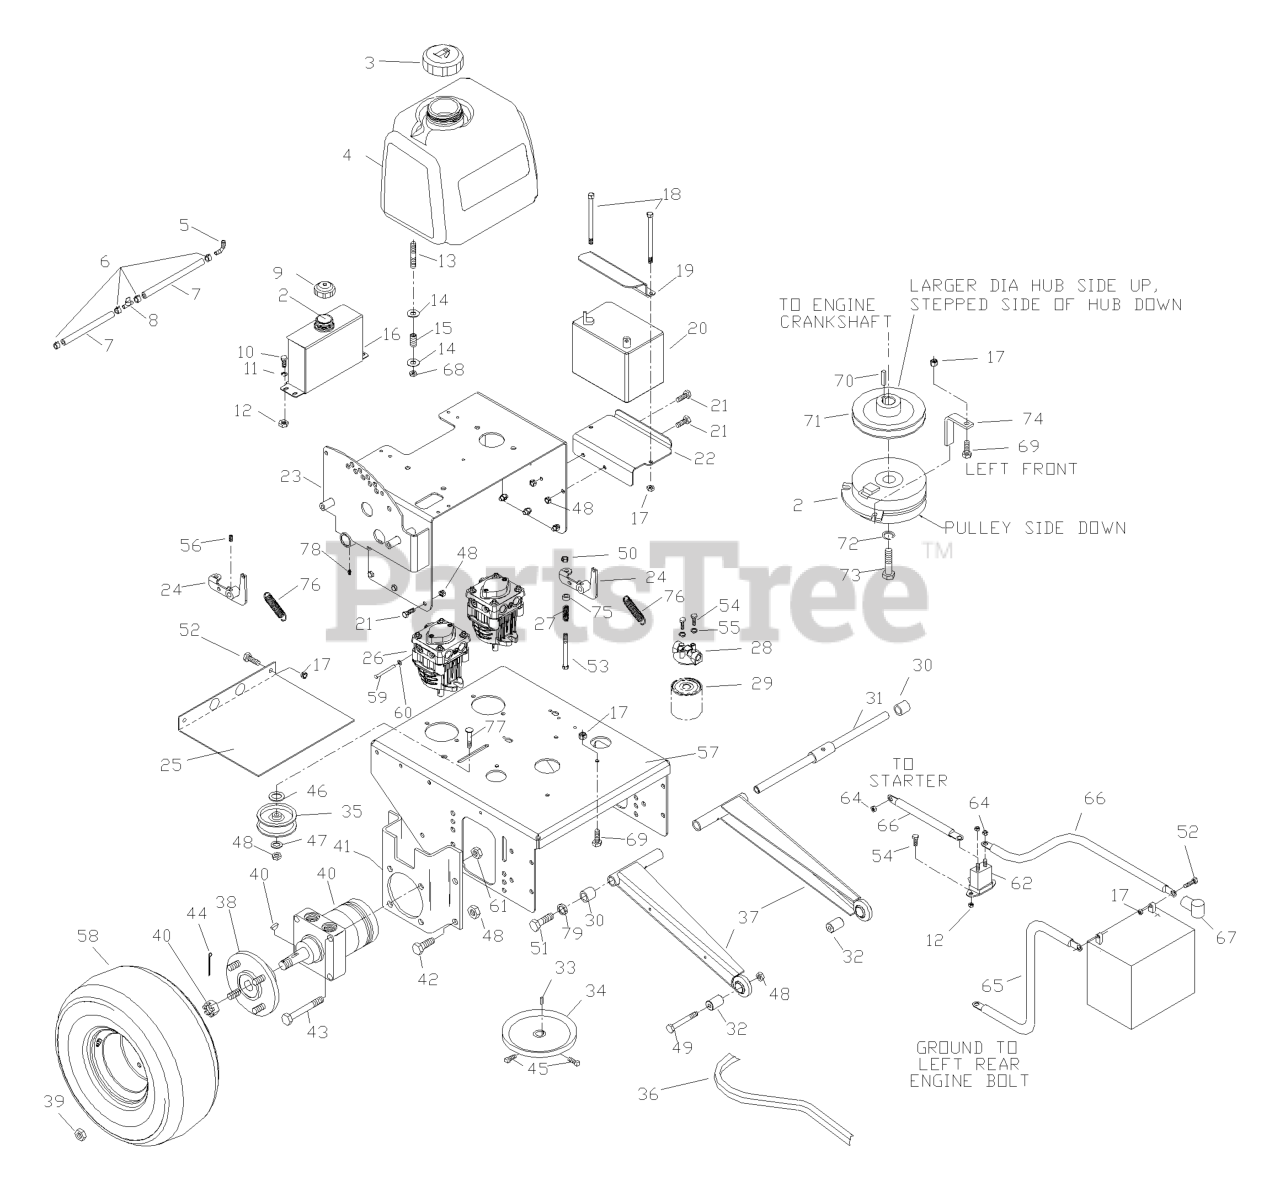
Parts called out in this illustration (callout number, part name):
1	CABLE, THROTTLE (17 KAW.)
3	FUEL CAP ANTI-SPLASH
5	HOSE BARB 90 DEGREE
6	HOSE CLAMP
7	GAS LINE 10"
8	FUEL VALVE
9	HYDRAULIC CAP
10	HCS 1/4C X 3/4 HCS
11	WASHER 1/4 FLAT
12	NUT 1/4C CENTER LOCK
13	STUD, 5/16C
14	WASHER 5/16 FLAT
16	OIL TANK BLK
17	NUT 5/16C CENTERLOCK
18	BOLT - 5/16 X 7
19	BATTERY STRAP
20	BATTERY WET NOT SELLABLE
21	SCREW 3/8C X 3/4 HEX CAP
22	BATTERY TRAY
23	TANK SUPPORT
24	PUMP ARM WELDMENT
25	LOWER BELT SHIELD
26	PUMP
28	FILTER HEAD
29	HYDRAULIC OIL FILTER
31	STRUT SHAFT
32	FRONT SPACER
33	KEY 5 MM SQ X 25 MM
35	IDLER PULLEY
36	TRANSMISSION BELT
37	STRUT WELDMENT
38	HUB.WHEEL.ZTR
39	LUG NUT 1/2F
40	WHEEL MOTOR
40	SEAL KIT - GEN I
41	MOTOR MOUNT
42	HCS 1/2C X 1 1/4 SERRATED HEAD
43	HCS 1/2C X 2 3/4
44	COTTER PIN
45	SCREW 5/16C X 5/8 SQ HEAD
46	WASHER 1/2 FLAT
47	WASHER 3/8 FLAT
48	NUT 3/8C CENTERBLOCK
49	HCS 3/8C X 2 1/4
50	NUT 3/8-16 NYLOC
51	HHCS 1/2-13 X 1
52	HCS 5/16C X 3/4
53	HEX SCREW 3/8-20 X 2.75
54	HCS 1/4C X 5/8
55	LOCKWASHER 1/4"
56	5/16C X 5/8 "V" POINT
58	TIRE/WHEEL ASSY
58	TIRE.TURF.SAVER.18X7.5-8
58	VALVE STEM TR-412
58	WHEEL
59	CLEVIS PIN
60	NUT PUSH
61	NUT 1/2-13 HEX NYLOC ZD
64	NUT.1/4-20.HEX.NYLOC.ZD
65	CABLE-NEGATIVE
66	CABLE POSITIVE, LONG
68	NUT 5/16 NYLOC
69	HCS 5/16C X 1 3/4
70	KEY 1/4 SQ X 1 1/8
72	WASHER 7/16 LOCK
73	BOLT 7/16F X 2 1/2
74	CLUTCH TIE DOWN
76	SPRING-TRANS
77	RHSNB 3/8C X 2
78	ZERK
79	WASHER 1/2" SPLIT LOCK
